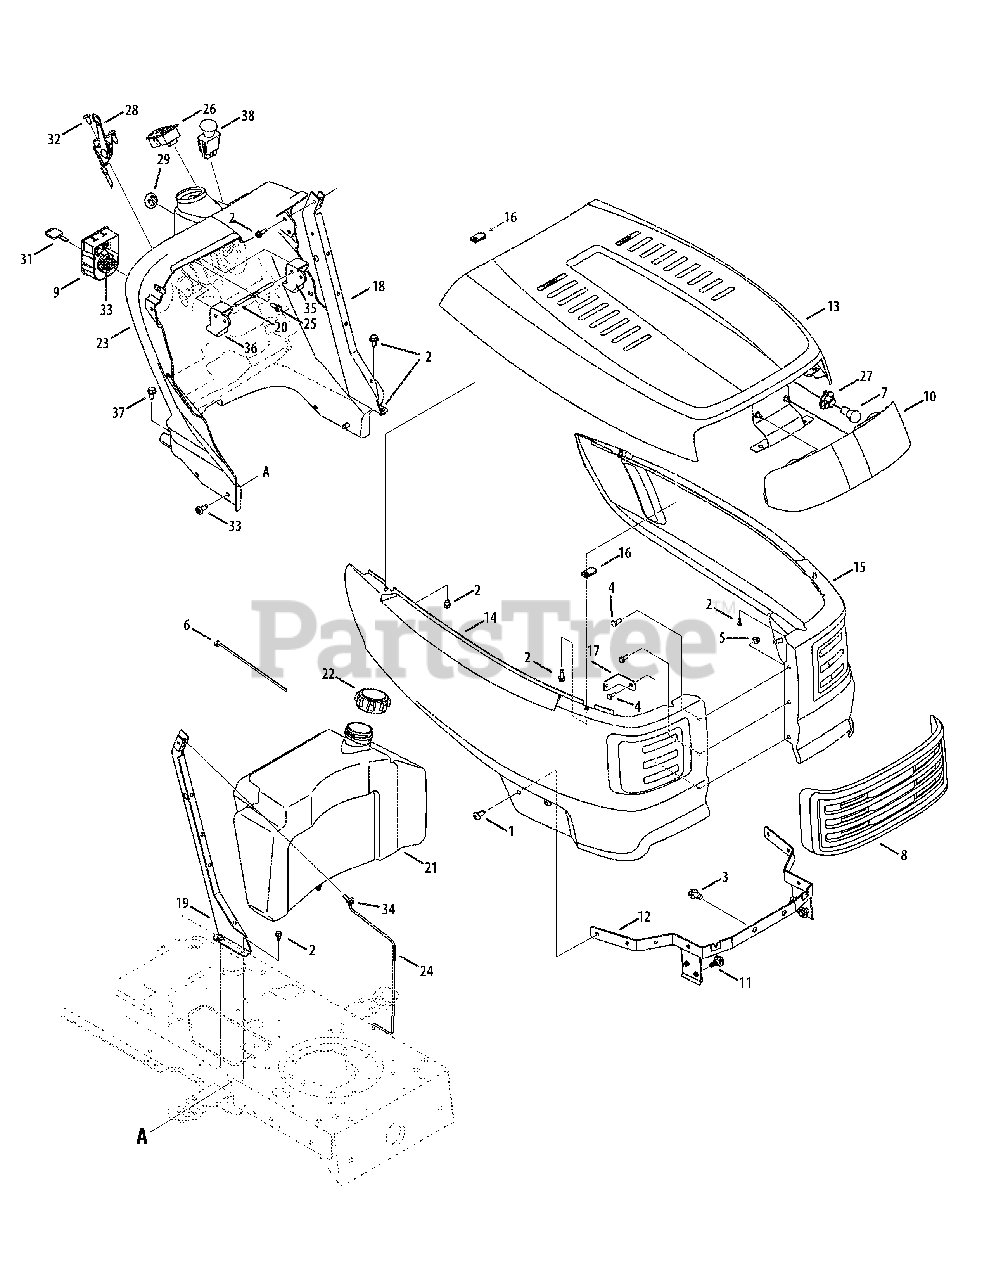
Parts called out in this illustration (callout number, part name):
1	Screw, 5/16-18, .375
2	Screw, 1/4-20, 0.500
3	Screw, 5/16-18, 0.625
4	Screw, 1/4-20, 0.620
5	Flange Lock Nut, 1/4-20
6	Cable Tie, 3/16 x .05 x 7.4
7	Headlamp, 12V
8	T-Style Grill Insert
9	Switch Housing
11	Screw, Shldr, .43 x .29, 5/16-18
16	T-Style Hood Fastener
21	Fuel Tank, 2.5 gal.
22	Fuel Tank Cap
23	Dash Panel, T-Style w/ Electric PTO
24	Gas Tank Support Rod
25	Screw, 1/4-15, .750
26	Hour Meter / Service Indicator
27	Lamp Socket
28	Throttle/Choke Control, 25.0
30	Module, Ignition Switch
31	Key
31	Key w/ Plastic Grip
32	Screw, 1/4-14, 0.625
33	Screw, 5/16-18, 0.750
34	Screw, 1/4-20, 0.750
35	Dash Brake Lever
36	Dash Cruise Lever
37	Screw, 5/16-18 x 0.500
38	Electric PTO Switch
